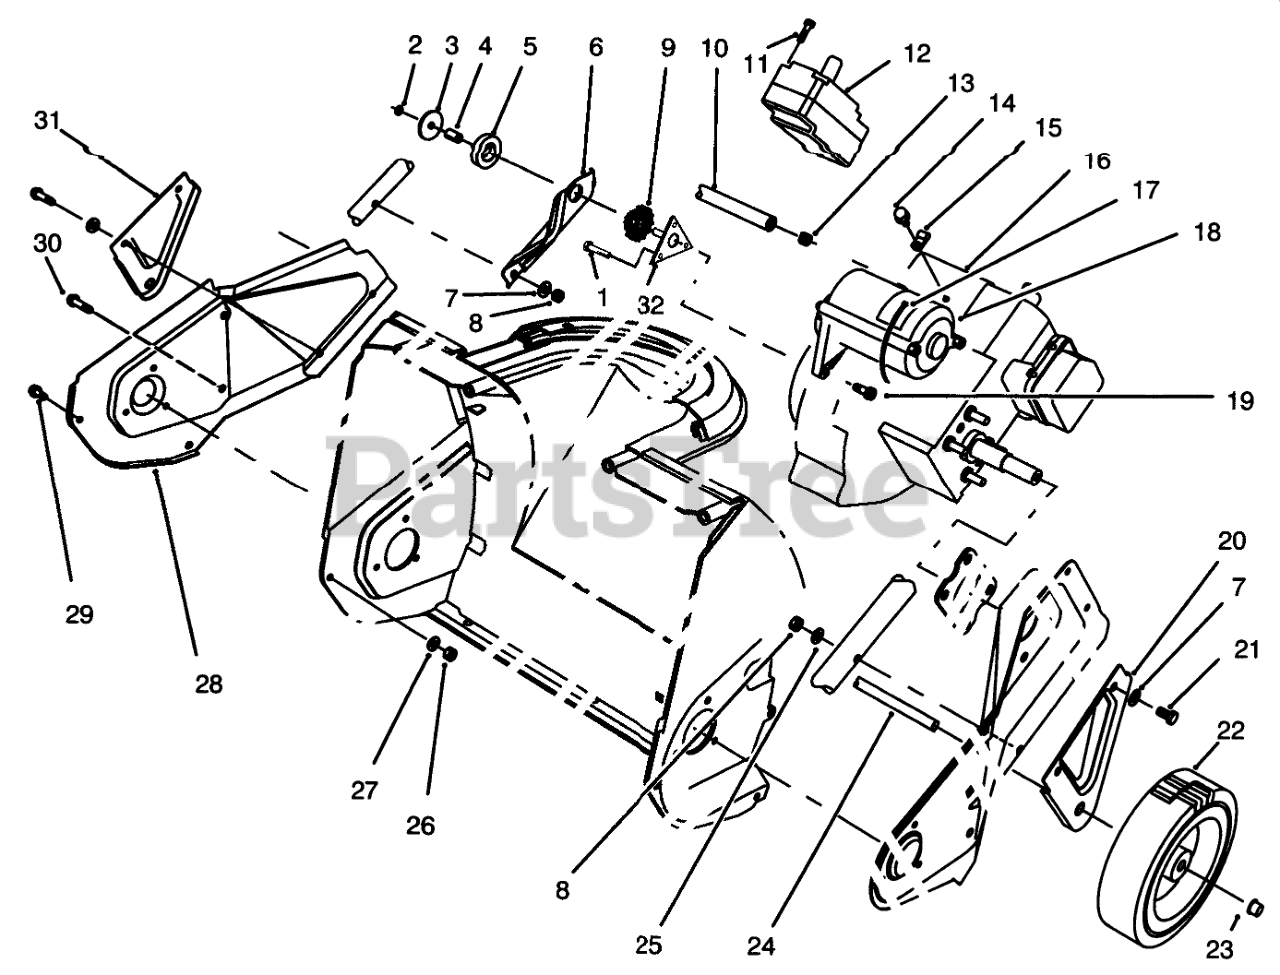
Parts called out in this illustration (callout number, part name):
1	SCREW X
2	NUT-LOCK, NI
3	WASHER-FLAT
4	SPACER-TUBULAR
5	Ring-Isolator
6	Support-Engine
7	WASHER-FLAT
8	NUT-LOCK, NI
9	BUSHING-ISOLATOR
10	LINE-GAS
11	SCREW-PLASTITE
12	ASM-Switch Housing
13	CLAMP-HOSE
14	SCREW-HWH
15	CLAMP
17	TIE-CABLE
18	ASM-Switch Housing
19	SCREW-HH, TORX
20	Bracket-Wheel
21	SCREW-HH
22	WHEEL
23	RETAINER-PUSH ON
25	WASHER
26	NUT-LOCK, NI
27	WASHER-FLAT
28	Sideplate-RH
30	SCREW-PLASTIC
31	Bracket-Wheel
32	BRACKET AND STUD ASM
